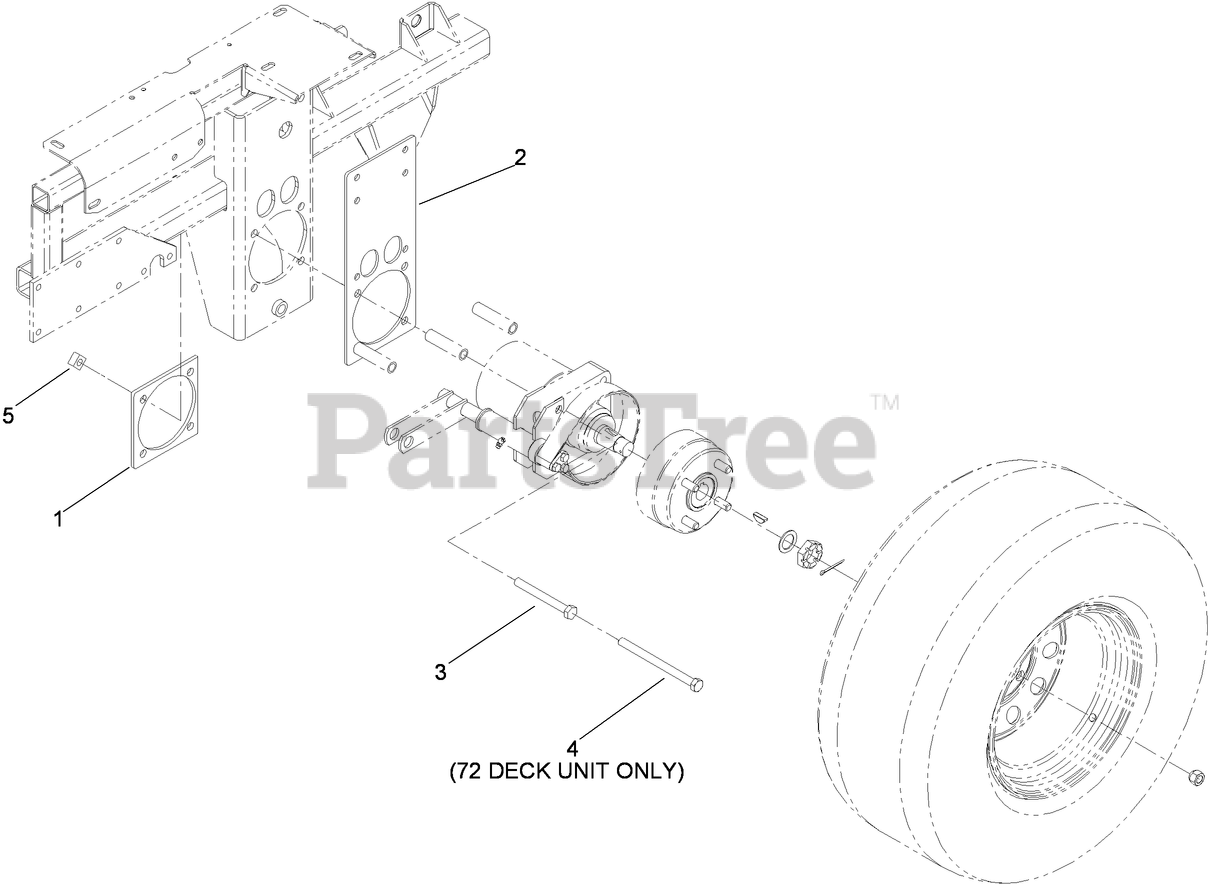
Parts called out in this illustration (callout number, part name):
1	PLATE-REINFORCEMENT
2	PLATE-CHANNEL, OUTSIDE
3	SCREW-HH
4	SCREW-HH
5	NUT-SQUARE, SPECIAL
